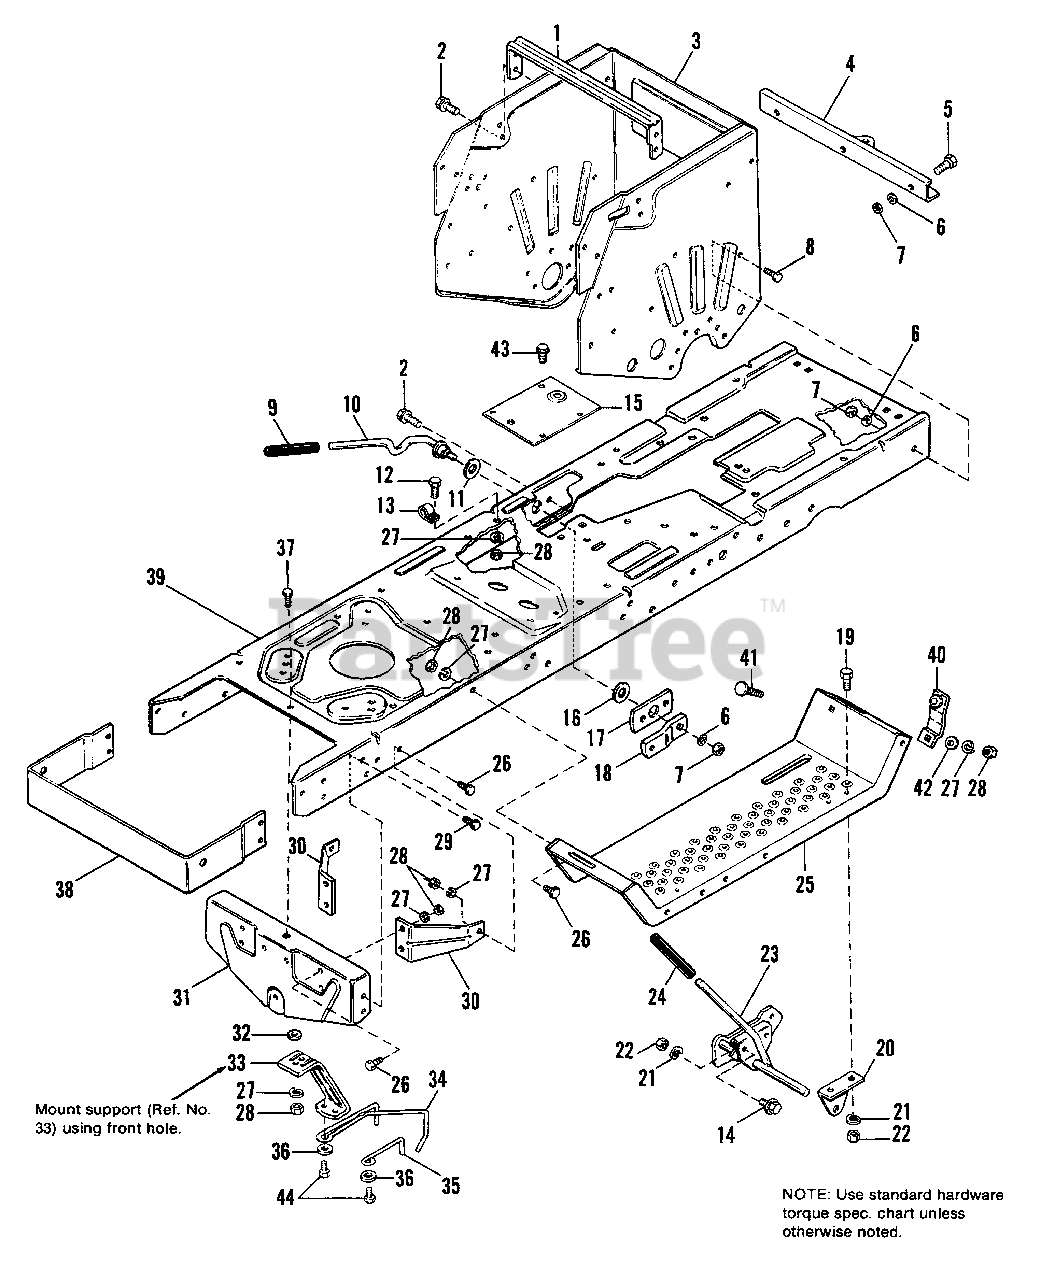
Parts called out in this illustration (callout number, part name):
1	BRACE, Seat
2	SCREW, Taptite, 5/16-18 x 1/2
3	SUPPORT, Axle Wrapper
4	BAR, Draw
5	CAPSCREW, Hex, 3/8-16 x 1
6	LOCKWASHER, 3/8
7	NUT, Hex, 3/8-16
8	CAPSCREW, Hex, 3/8-16 x 3/4
9	GRIP, Handle
10	HANDLE, Lift
12	CAPSCREW, Hex, 5/16-18 x 1-1/4
14	CAPSCREW, Hex Washer Hd., 1/4-20 x 5/8
15	PLATE, Adaptor
17	BAR, Support
18	ARM, Support
19	CAPSCREW, Hex, 1/4-20 x 5/8
20	SUPPORT, Clutch
21	LOCKWASHER, 1/4
22	NUT, Hex, 1/4-20
23	LEVER ASSY., Clutch
24	GRIP, Handle
26	CAPSCREW, Hex, 5/16-18 x 3/4
27	LOCKWASHER, 5/16 (Qty. 16 used on early models)
28	NUT, Hex, 5/16-18 (Qty. 16 used on early models)
29	SCREW, Taptite, 5/16-18 x 3/4
30	BRACE, Axle Support
31	SUPPORT, Axle
32	WASHER, Plain, 11/32-1 x 10 Ga.
36	WASHER, 1/4
37	CAPSCREW, Hex Hd., 5/16-18 x 1
39	FRAME
40	LATCH ASSY.
41	CARRIAGE BOLT, 5/16-18 x 3/4
42	WASHER, Plain, 5/16
43	SCREW, Taptite, 1/4-20 x 1/2
44	CAPSCREW, Hex, 5/16-18 x 7/8
